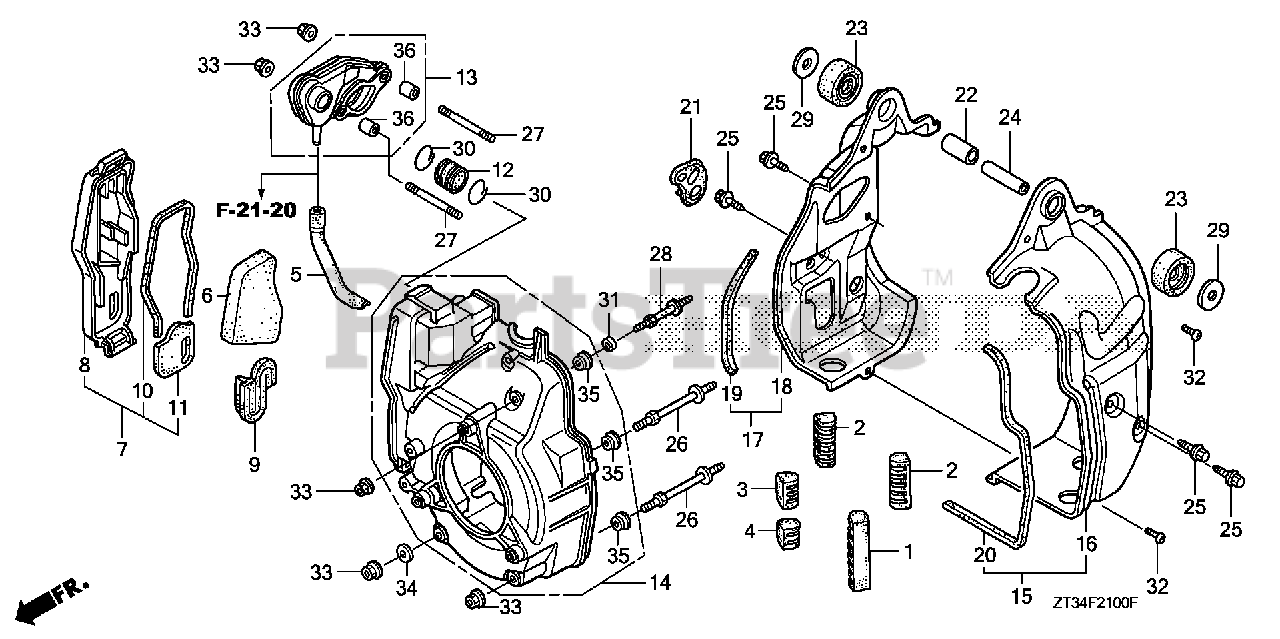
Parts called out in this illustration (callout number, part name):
5	TUBE, BREATHER
6	ELEMENT, AIR CLEANER
7	COVER, AIR CLEANER
8	COVER, AIR CLEANER
9	RUBBER, AIR CLEANER
10	SEAL A, AIR CLEANER COVER
11	SEAL B, AIR CLEANER COVER
12	TUBE, AIR CLEANER CONNECTING
13	JOINT, AIR IN.
14	COVER, FAN
16	SHROUD, R.
18	SHROUD, L.
21	RUBBER, OIL CHECK
22	COLLAR D, INSULATOR
23	INSULATOR, SHROUD
24	COLLAR B, INSULATOR
25	BOLT, FLANGE (5X10)
26	BOLT A, STUD
27	BOLT, STUD (5X81)
28	BOLT B, STUD
29	WASHER, SPROCKET SETTING
30	CLIP (28MM)
31	COLLAR, DISTANCE
32	SCREW, PAN (4X6)
33	NUT, FLANGE (5MM)
34	WASHER, PLAIN (5MM)
35	COLLAR, REFLECTOR SETTING
36	COLLAR, AIR CLEANER HOUSING
